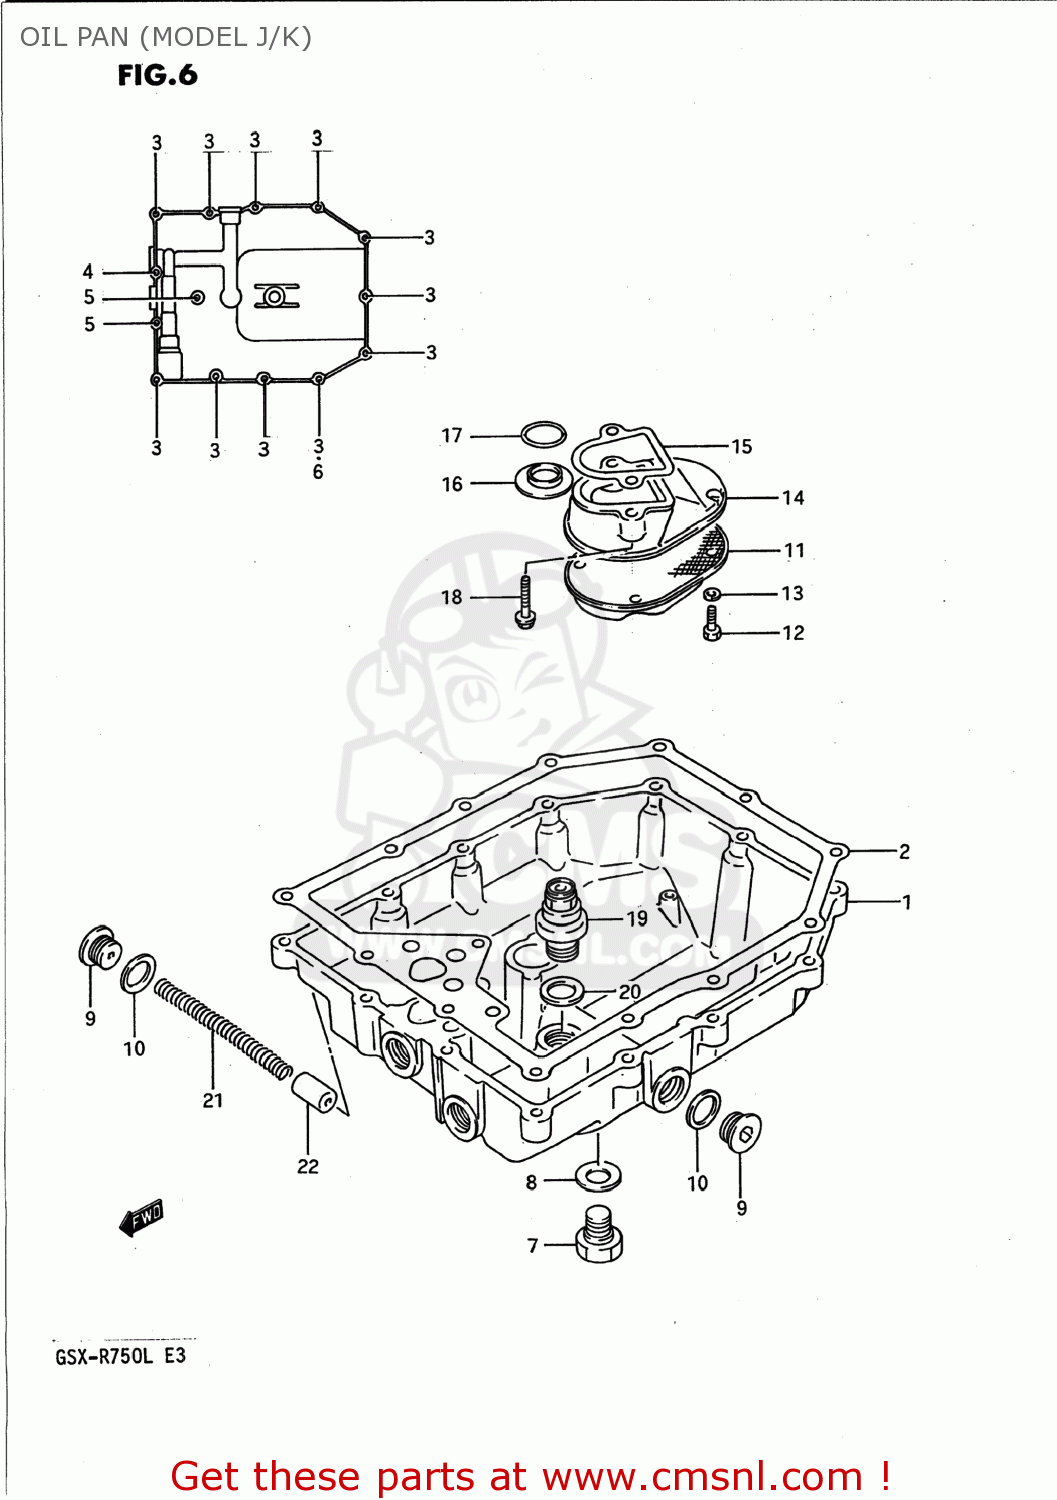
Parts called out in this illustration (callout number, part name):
1	PAN,OIL
2	GASKET,OIL PAN (NAS)
3	BOLT
4	BOLT
5	BOLT
6	GASKET(5.8X11X1.2) (NAS)
7	PLUG
8	GASKET(14X19.2X2) (NAS)
9	PLUG
10	GASKET(16X22X2) (NAS)
11	STRAINER,ENGINE OIL
12	BOLT
13	WASHER,LOCK
14	PROTECTOR,OIL STRAINER
15	GASKET,OIL STRAINER PROTECTOR (NAS)
16	GASKET,OIL OUTLET (NAS)
17	O RING(D:3.2,ID:17.8)
18	BOLT
19	VALVE ASSEMBLY,OIL RELIEF
20	GASKET(16X22X2) (NAS)
21	SPRING
22	PLUNGER,OIL CONTROLL
